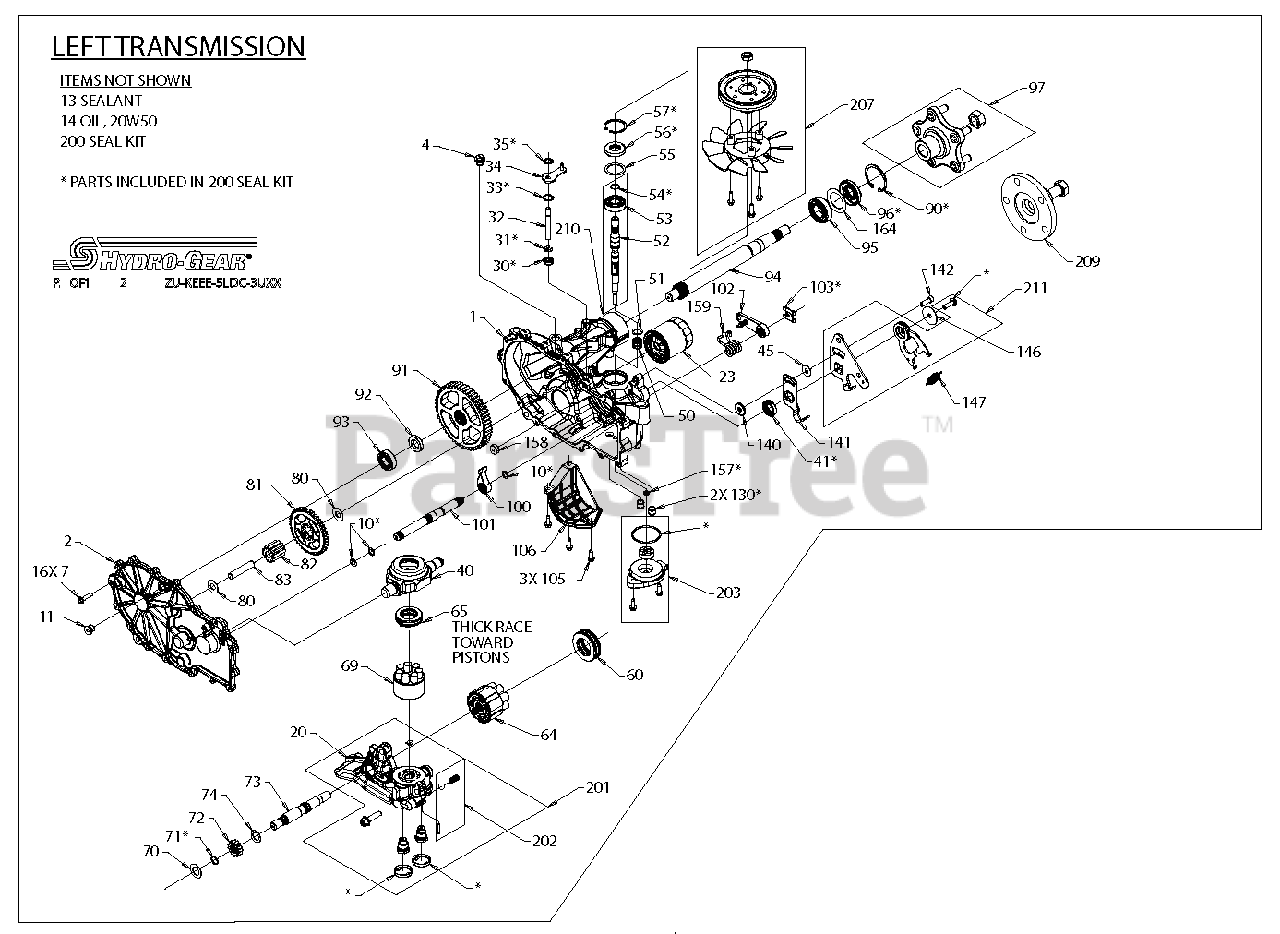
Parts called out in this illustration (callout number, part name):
23	FILTER OIL
30	SEAL, LIP .375 X .75 X .25
31	RING, RET .375 EXTERNAL
35	RING, RTNG .375 EXT
40	TRUNNION, SWASHPLATE
41	SEAL, LIP 18 X 32 X 7
51	WASHER FLAT .59 X .79 X .04
55	WASHER 1.23 X 1.56 X .04
56	SEAL, LIP 17 X 40 X 7
57	RING, RET 2.06 INT
80	WASHER .5 X 1.0 X .03
95	BRG, BALL 1.0 X .52 X .15 OPEN 6205M
96	SEAL, LIP TC4 1.0 X 2.06 X .38
97	KIT, HUB, 5 BOLT
100	PAWL, BRAKE
101	SHAFT, BRAKE
